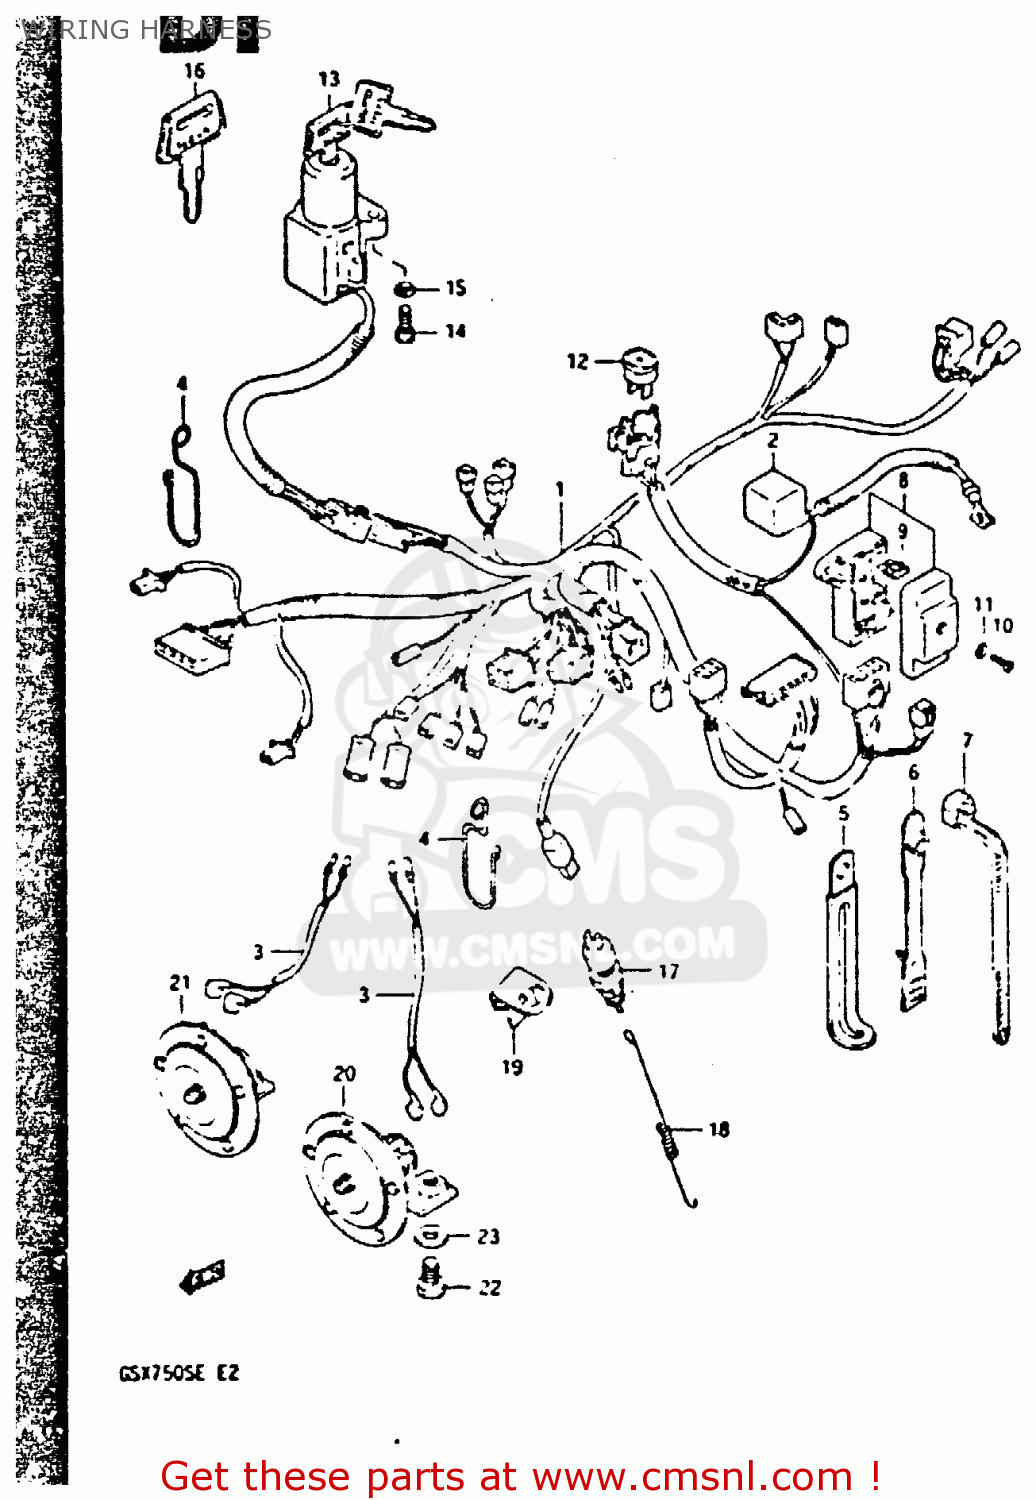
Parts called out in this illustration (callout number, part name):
1	WIRING HARNESS
2	CAP,BATTERY PLUS TERMINAL
3	LEAD WIRE, HORN
4	GUIDE,WIRING HARNESS
5	CLAMP
6	CLAMP,L:88
7	CLAMP(L:95)
8	BOX ASSEMBLY,FUSE
9	FUSE(10A)
10	SCREW
11	WASHER, LOWER
12	BREAKER ASSY,CIRCUT
13	SWITCH ASSY, IGNITION
14	BOLT
15	LOCK WASHER
16	KEY,BLANK
17	SWITCH ASSEMBLY,STOP LAMP
18	SPRING
19	PLATE, STOP LAMP SWITCH
20	HORN, HIGH PITCHED
21	HORN, LOW PITCHED
22	BOLT
23	WASHER
